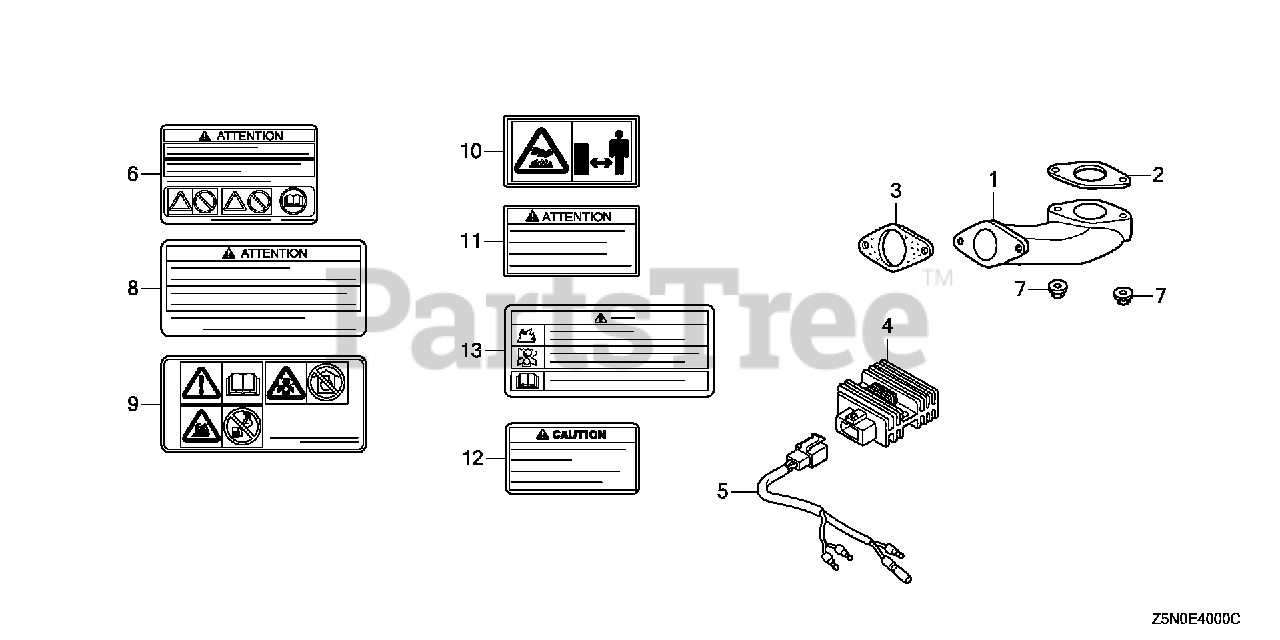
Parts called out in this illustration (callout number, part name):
6	MARK, OPERATOR CAUTION (FRENCH)(MADE IN THAI)
8	MARK, OPERATOR CAUTION (FRENCH)(MADE IN THAI)
9	MARK, OPERATOR CAUTION (PICTOGRAPH)
10	MARK, EX. CAUTION (PICTOGRAPH)
11	MARK, EX. CAUTION (FRENCH)
